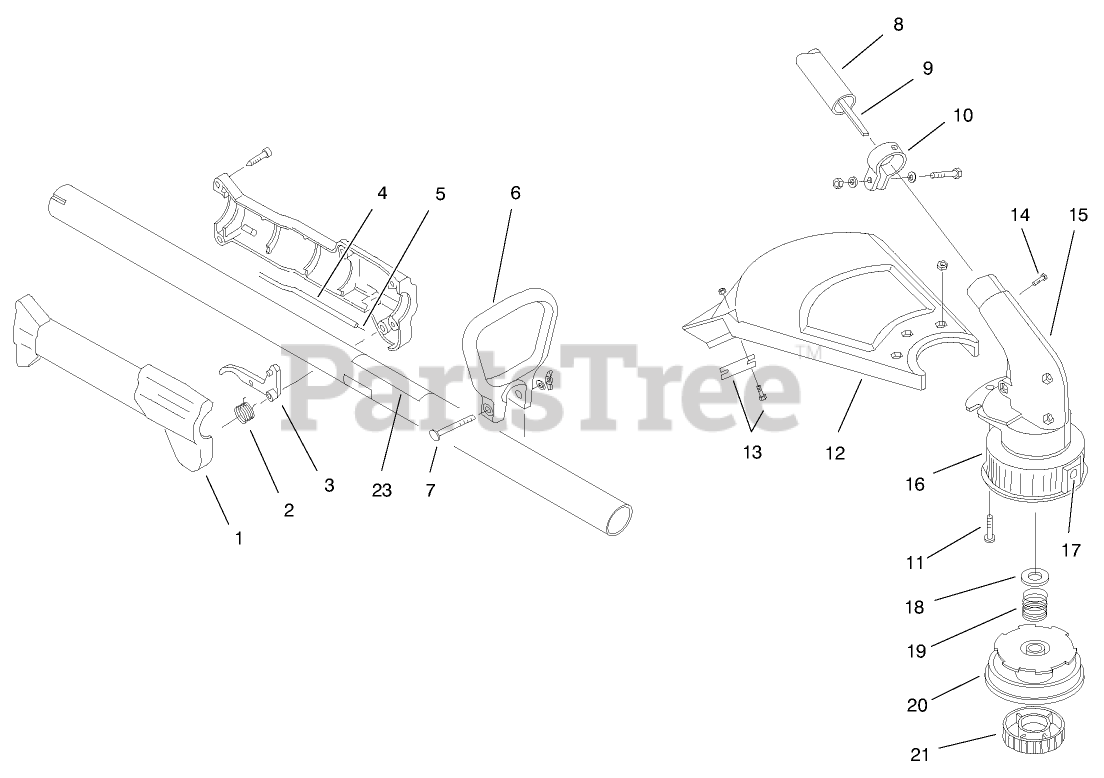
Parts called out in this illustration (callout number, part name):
7	HARDWARE - D-HANDLE
9	SHAFT - FLEX, 48.94
10	CLAMP ASM - UPPER
11	ASM - GUARD MTG SCREW
13	BLADE ASM
16	OUTER SPOOL EYELET ASM
17	EYELET
18	RETAINER WASHER
19	SPRING
20	REEL - INNER
21	KNOB ASSEMBLY-SMALL BUMP
